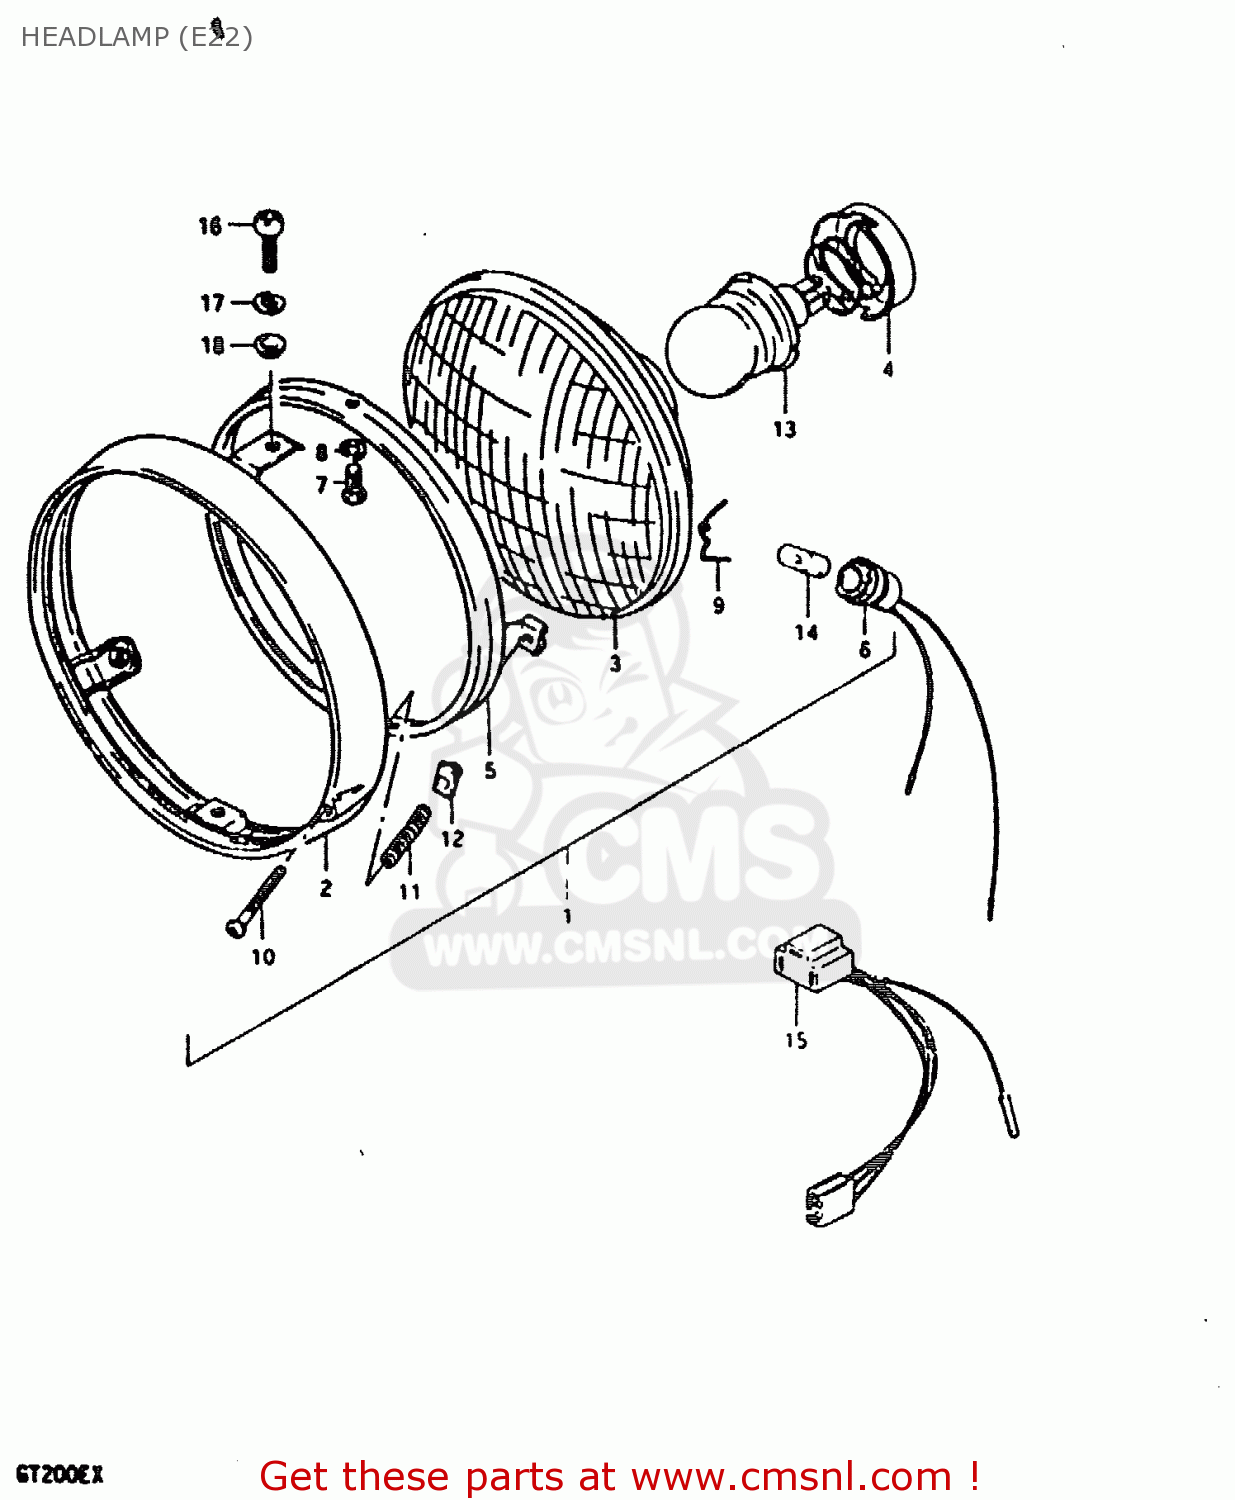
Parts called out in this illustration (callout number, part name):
1	HEADLAMP ASSY
2	RIM,HEADLAMP
3	UNIT
4	SETTER,BULB
5	RETAINER,HEADLAMP
6	SOCKET
7	SCREW
8	LOCK WASHER
9	SPRING
10	SCREW,HEADLAMP ADJUST
11	SPRING
12	NUT
13	BULB(12V45/40W)
14	BULB(12V4W)
15	LEAD WIRE,HEADLAMP
16	SCREW
17	WASHER,LOCK
18	WASHER
